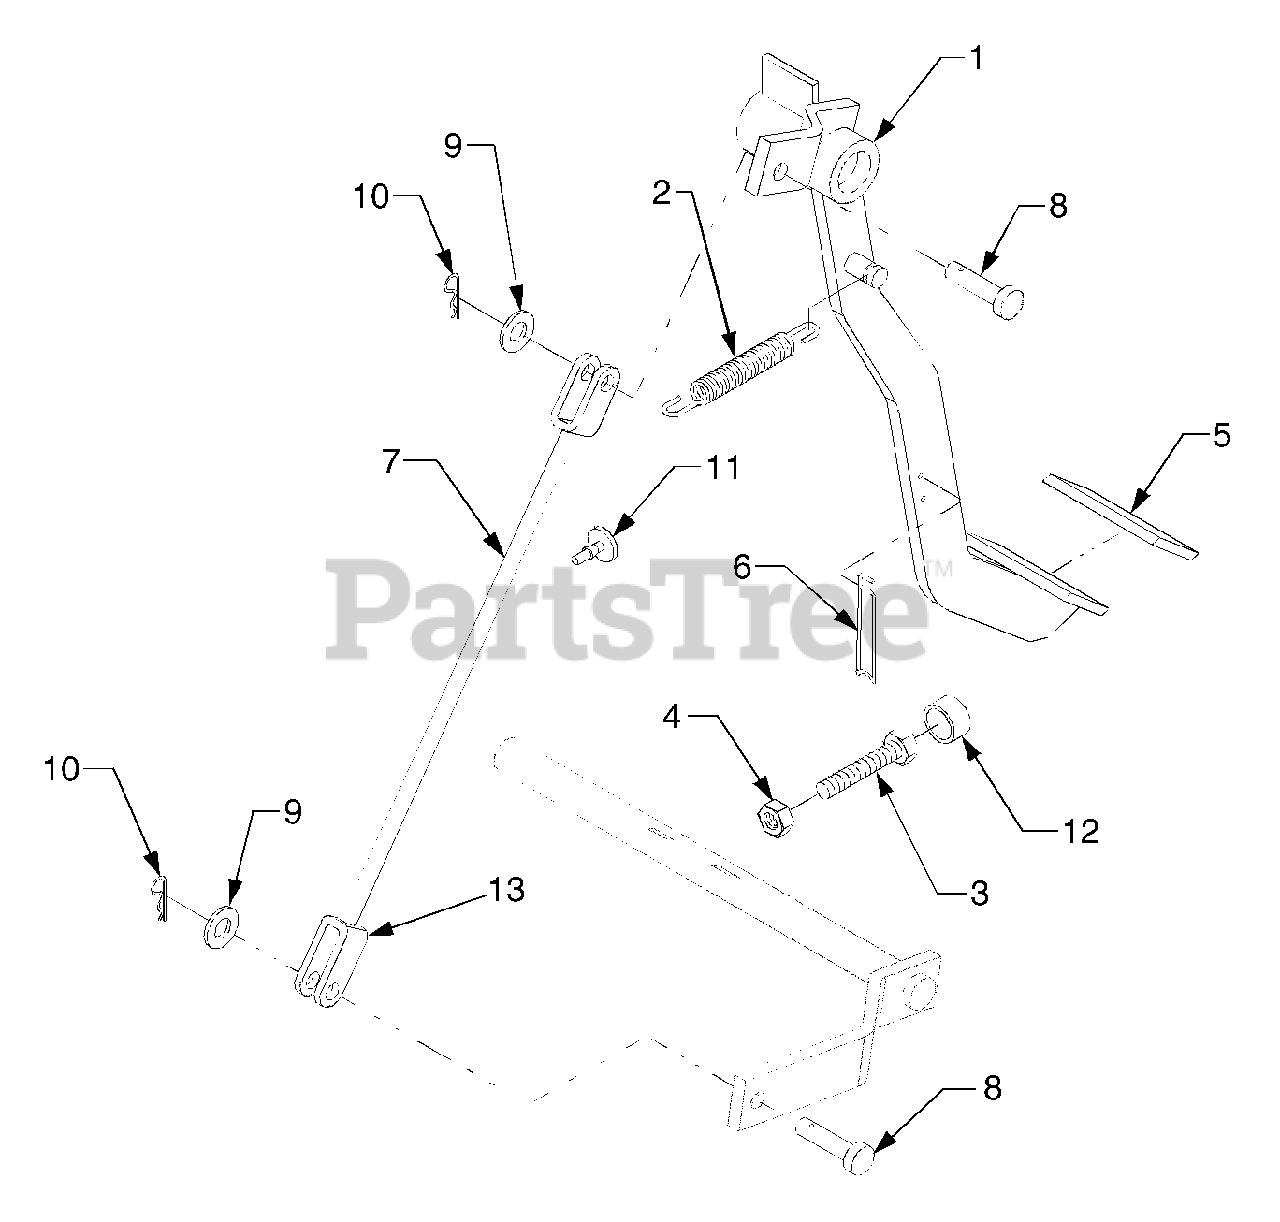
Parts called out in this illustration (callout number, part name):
1	Pedal, Clutch
2	Spring, Brake
9	Washer, Plain
11	Cushion, Pedal
12	Cushion (Clutch)
